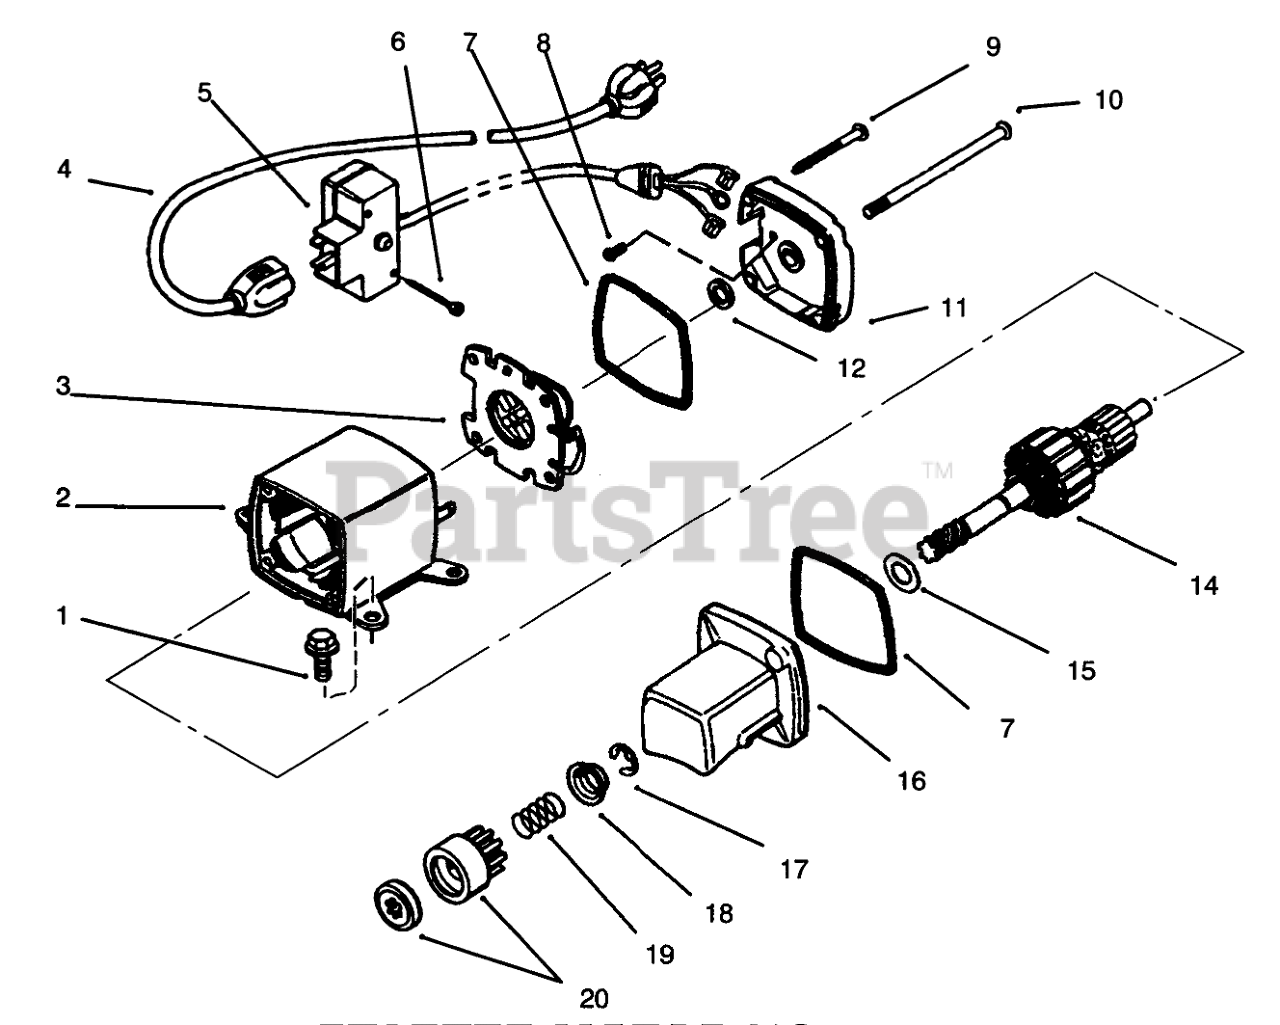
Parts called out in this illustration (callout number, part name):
1	Screw (T-30, 1/4-20 x 23/32)
2	Housing Asm
3	Brush Card ASM
4	Cord-Extension (10-6)
5	Switch Box ASM
8	Screw-Ground
9	Screw-Ground
10	Bolt-Case
11	Cap-Commutator End Asm (Incl. Ref. #7)
12	Washer-Thrust
14	Armature
15	Washer-Thrust
16	Cap-Drive End (Incl. Ref. #7)
17	Retainer-Ring
18	Retainer-Spring
19	Spring-Anti Drift
20	Nut & Gear
